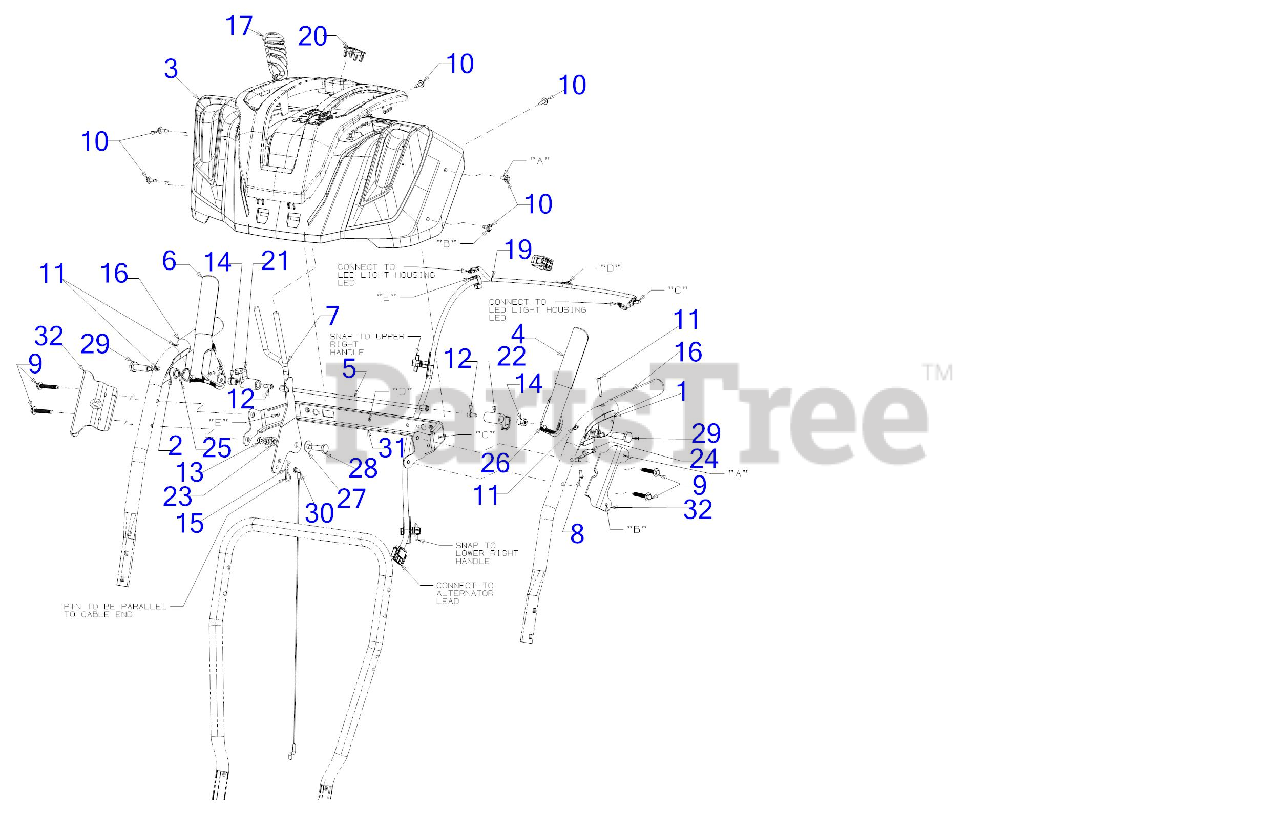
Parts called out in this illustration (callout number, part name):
1	CLUTCH LOCK HANDLE ASSEMBLY (LH)
2	CLUTCH LOCK HANDLE ASSEMBLY (RH)
3	HANDLE PANEL ASSEMBLY
4	HANDLE ASSEMBLY (LH)
6	HANDLE ASSEMBLY (RH)
8	SCREW #8-16 x .50
9	SCREW 1/4-20 x 1.625
10	SCREW M6-1 x .625
11	SCREW #10-24 x 1.375
12	SCREW 1/4-20 x .50
13	FLANGE LOCK NUT
14	HEX NUT W/PATCH
15	INTERNAL COTTER PIN
17	PTO HANDLE GRIP .355 ID
19	HEADLIGHT HARNESS
20	PANEL SWITCH PLUG
22	CLUTCH LOCK CAM
23	COMPRESSION SPRING
24	CLUTCH SPRING
25	TORSION SPRING
26	RUBBER BUMPER
27	FLAT WASHER
28	SHOULDER SCREW
29	SHOULDER SCREW .437 x 1.345 1/4-20
30	SPEED SELECTOR CABLE (PLASTIC)
